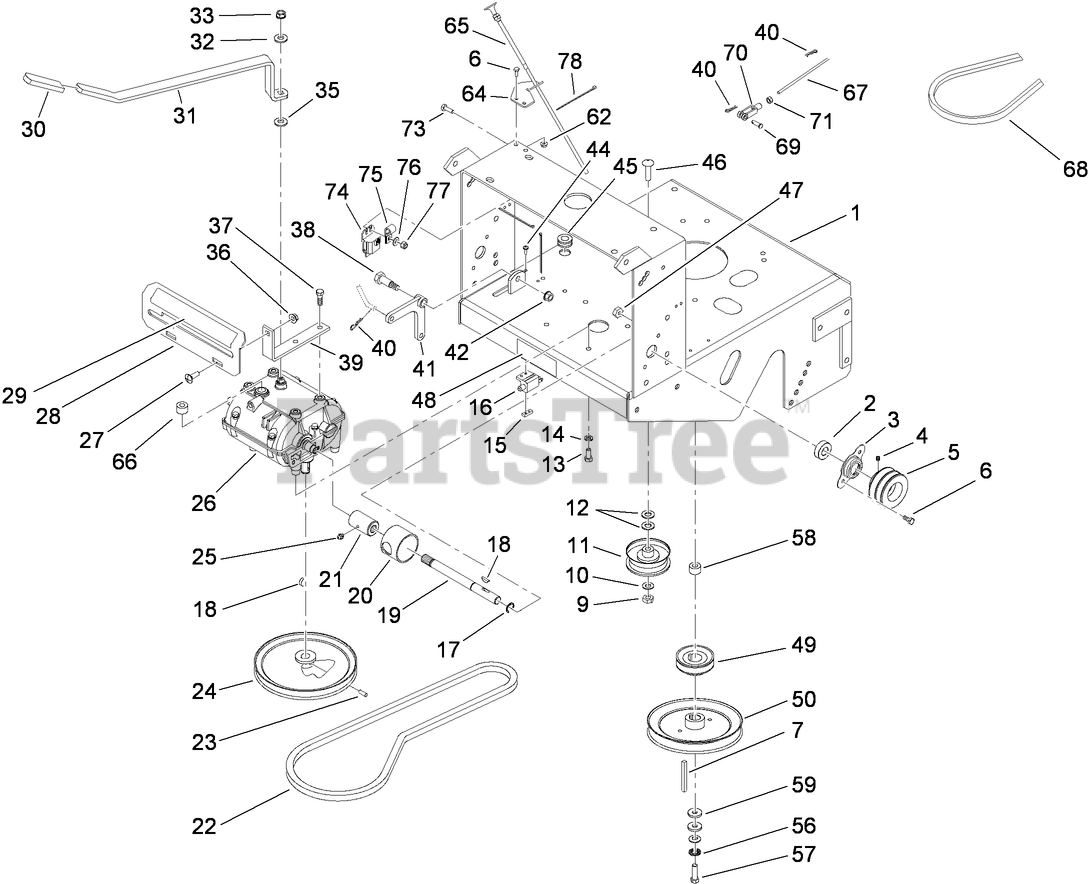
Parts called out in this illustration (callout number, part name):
1	DECK-ENGINE
2	BEARING-SHAFT
3	FLANGE-OUTPUT
4	SCREW-SET
5	SHEAVE-TRANSMISSION
6	SCREW-HH
9	NUT-LOCK, NI
10	WASHER-FLAT
11	PULLEY-IDLER, FLAT
12	WASHER-FLAT
13	SCREW-HH
14	WASHER-LOCK
15	PLATE-TAPPED
16	SWITCH-OPEN, NORMALLY
17	RING-RETAINING
18	KEY-WOODRUFF
19	SHAFT-TRANSMISSION
20	GUARD-COUPLER
21	COUPLER
22	V-BELT
23	SCREW-HSH
24	SHEAVE-TRANSMISSION
25	FITTING-GREASE
26	TRANSMISSION
27	BOLT-CARR
28	PLATE-SHIFT
29	DECAL-SPEED, GROUND
30	GRIP-LEVER
31	LEVER-SHIFT
32	WASHER-BELLEVILLE
33	NUT-LOCK
35	WASHER
36	NUT-HF
37	SCREW-HWH, THREAD CUT
38	BOLT-SHOULDER
39	BRACKET-PLATE, SHIFT
40	PIN-COTTER
41	BELLCRANK
42	NUT-HF
44	SCREW-PPH
45	GROMMET
46	SCREW-CARR
47	NUT-LOCK, NI
48	DECAL-CAUTION
49	Sheave-Transmission
50	Sheave
56	WASHER-SPRING
57	SCREW-HH
58	SPACER-CLUTCH
59	WASHER
62	NUT-HF
64	Bracket-Cable, Choke
65	Cable-Choke
66	Switch-Start, Neutral
67	ARM-ASSIST, LINKAGE
68	BELT-V
69	PIN-CLEVIS
70	YOKE-ADJUSTABLE
71	NUT-HEX
73	SCREW-HH
74	MODULE-INTERLOCK
75	CLIP-LOOM
76	WASHER-FLAT
77	NUT-LOCK, NI
78	TIE-PLASTIC
